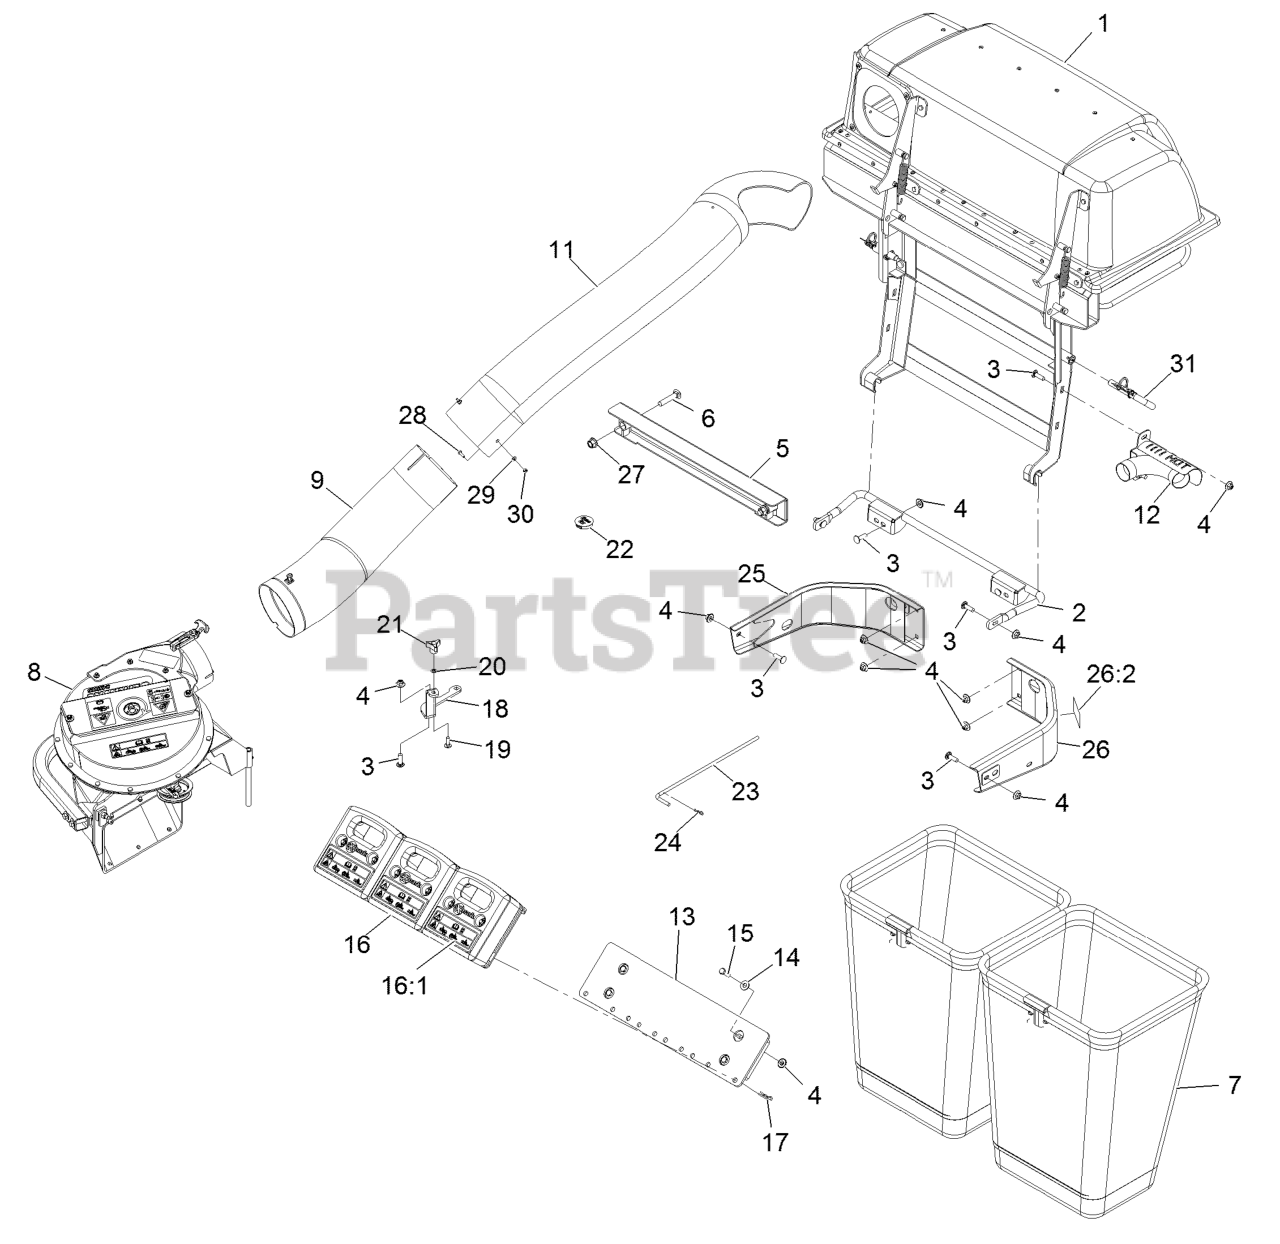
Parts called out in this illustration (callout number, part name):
2	MOUNT-BAGGER, LOWER
3	Bolt-Carriage 3/8-16 X 1 1/4
4	Nut-Nyloc 3/8-16 Flg
5	MOUNT-BAGGER, UPPER
6	SCREW-CARR
7	BAG AND FRAME ASM
8	ASM, BLOWER SMALL - SVC O
9	LOWER TUBE ASM
11	TUBE-UPPER
12	EXHAUST DIVERTER ASM
13	WLD, MOUNT TOEBOARD WEIGH
14	WASHER-FLAT
15	SCREW-HH
16	ASM,CAST WEIGHT
16:1	DECAL-WARNING WEIGHT
17	PIN-HAIR
18	BRACKET, SMALL UV BELT CO
19	BOLT-CARR
20	RING-RETAINING, BOLT
21	KNOB-3 PRONG
22	PLUG, BLACK NYLON 1.75
23	PIN,CHUTE PIVOT
24	PIN-COTTER
25	BUMPER-RH
26	LH BUMPER ASM
26:2	DECAL-WARNING
27	Nut-Lock 1/2-13
28	SCREW-HWH
29	WASHER-FLAT
30	NUT-LOCK, NI
31	PIN-MOUNT, BAGGER
